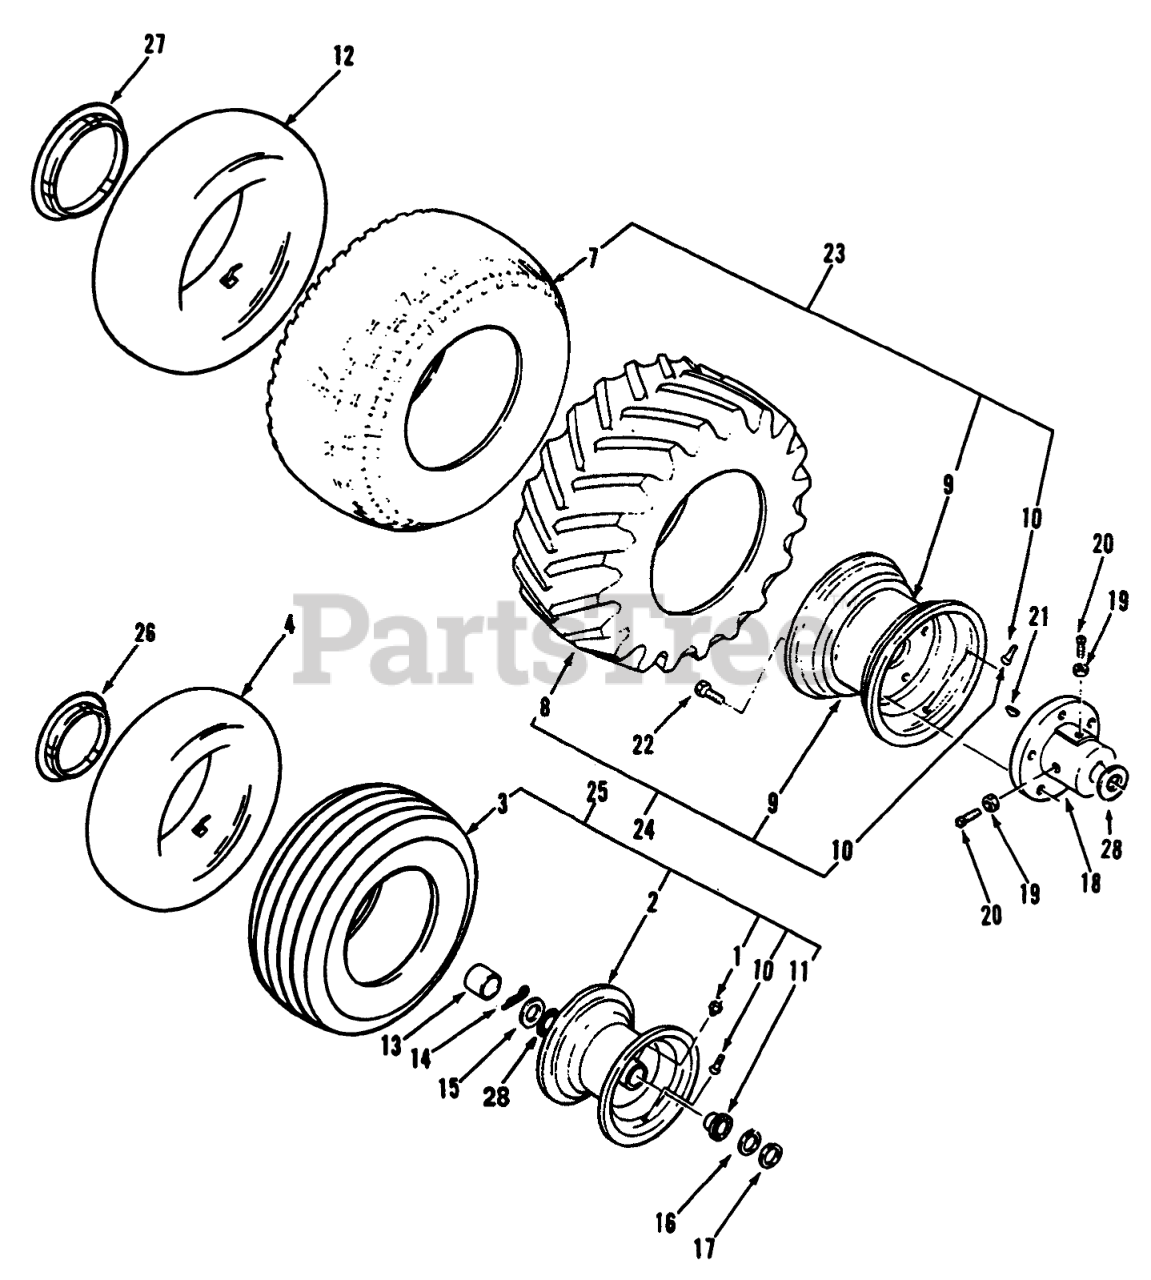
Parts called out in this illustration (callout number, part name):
1	ZERK-GREASE
2	Wheel-Front (Includes Item 1, 10, & 11
3	TIRE-15 X 6.00-6
7	TIRE
8	Tire-Cleat, Rear
9	WHEEL
10	VALVE
11	BEARING-WHEEL
12	TUBE-INNER
13	HUB CAP-FLAT BLACK
14	PIN-COTTER
15	WASHER-WHEEL
16	WASHER
17	WASHER-SHIM
18	Hub Rear
19	NUT-JAM
20	SCREW-SET, SQH
21	KEY-WOODRUFF
22	Lug Nut
23	ASM-Wheel& Tire
24	ASSY WHEEL & TIRE
25	ASM-Wheel & Tire
26	6"-HUB CAP LOGO
27	12"-HUB CAP LOGO
28	WASHER-THRUST
